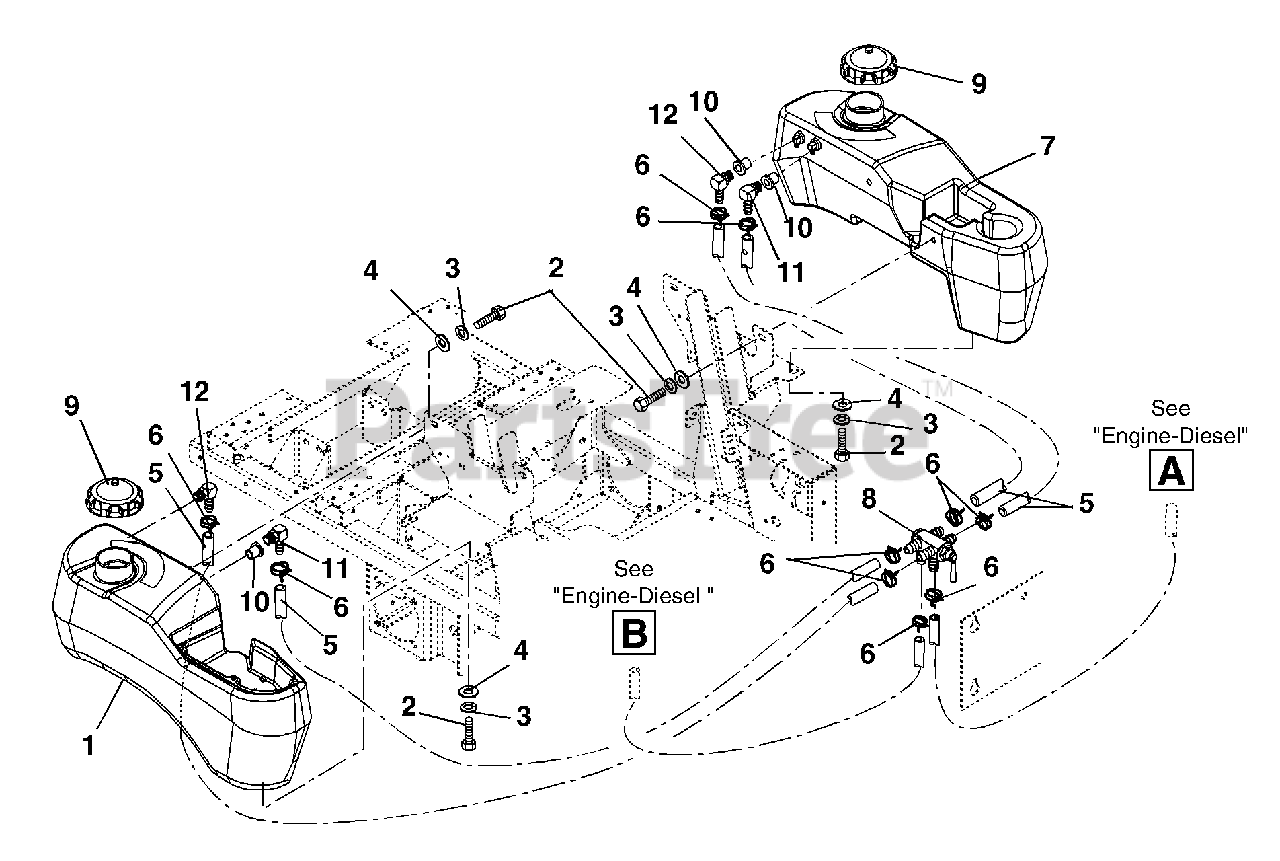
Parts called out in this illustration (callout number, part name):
1	Tank, Fuel-Right Hand (060, 061, 318, 319)
2	Bolt, Hex .31-18 x .75 Grade 5
3	Washer, Locking .31 x .078
4	Washer, Flat Steel .38 x .875 x .083
5	Hose, .31 ID (060, 061, 318, 319)
6	Clamp, Hose Wire .52/.55 (060, 061, 318, 319)
7	Tank, Fuel-Left Hand (with Return) (060, 061, 318, 319)
8	Valve, Fuel (060, 061, 318, 319)
9	Cap, Fuel (060, 061, 318, 319)
11	Fitting, Tank (060, 061, 318, 319)
12	Fitting, Tank (060, 061, 318, 319)
